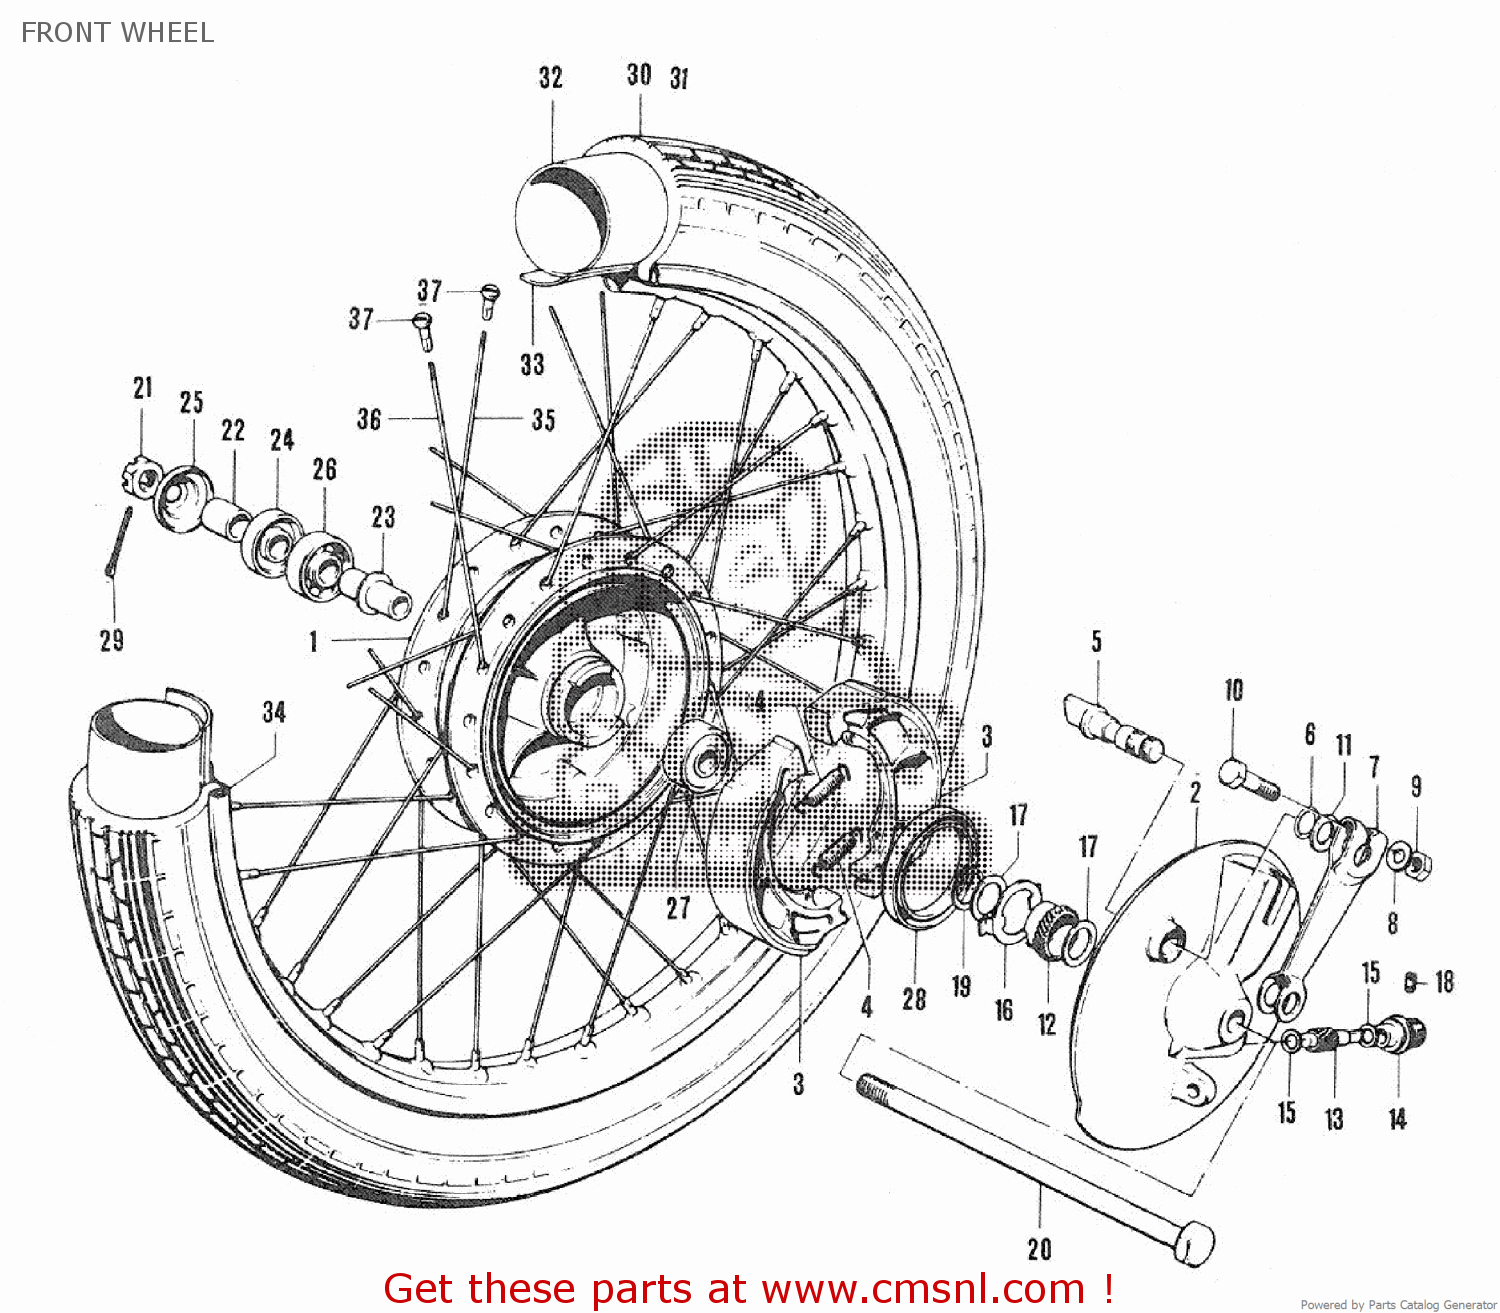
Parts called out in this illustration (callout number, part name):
1	HUB,FRONT
2	PANEL,FRONT HUB
3	SHOE,BRAKE
4	SPRING(L:34)
5	CAM,FRONT BRAKE
6	O RING(D:2.5,ID:11.4)
7	LEVER,FRONT BRAKE CAM
8	WASHER
9	NUT
10	BOLT
11	WASHER(12.5X20X1)
12	GEAR,SPEEDOMETER
13	PINION,SPEEDOMETER
14	BUSH,METER GEAR OUTER
15	WASHER (5.1X9X0.4)
16	DRIVER,SPEEDOMETER GEAR
17	WASHER(18.5X24X1)
18	SCREW
19	CIRCLIP
20	AXLE,FRONT
21	NUT 12MM
22	SPACER(12X18X19.4)
23	SPACER,FRONT HUB BEARING
24	OIL SEAL(17X38X5)
25	COVER,FR HUB DUST SEAL
26	BEARING
27	BEARING, RH
28	OIL SEAL
29	PIN
31	TIRE,FRONT
32	TUBE,INNER
33	PROTECTOR,WHEEL,INNER
34	SPOKE SET,FRONT
35	SPOKE,WHEEL
36	SPOKE,WHEEL
37	NIPPLE,SPOKE
